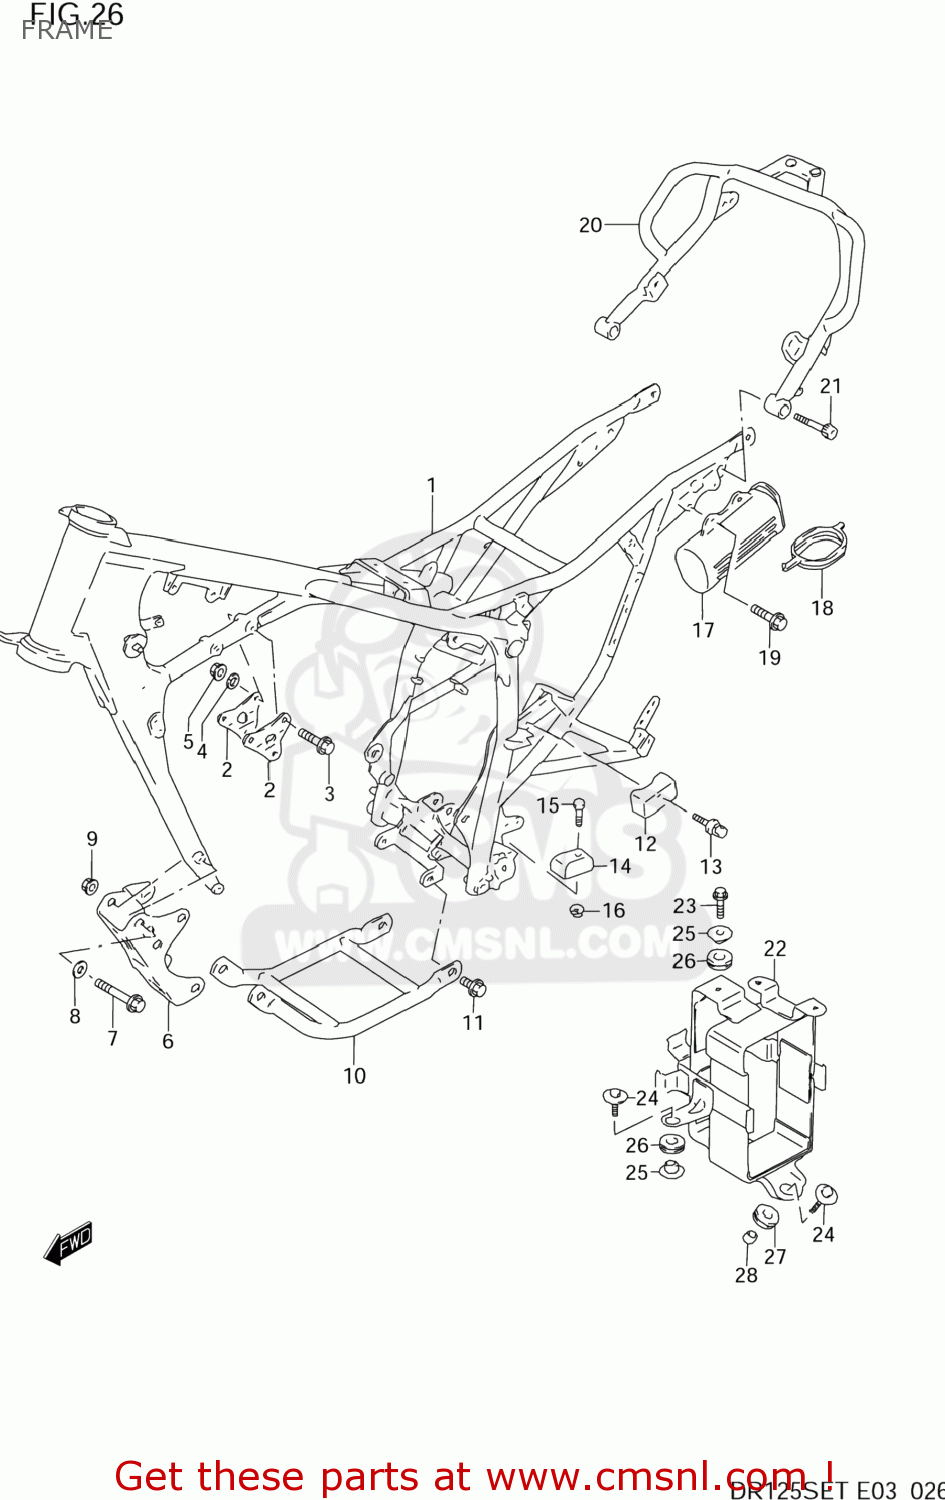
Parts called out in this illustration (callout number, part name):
1	FRAME COMP
2	PLATE,ENGINE MOUNT UPR
3	BOLT M8X52
4	LOCK WASHER
5	NUT
6	PLATE,ENGINE MOUNTING
7	BOLT(8X65)
8	LOCK WASHER
9	NUT
10	PROTECTOR COMP,ENGINE
11	BOLT
12	GUIDE,CH CONTROL UPR
13	BOLT
14	GUIDE,CH LENGTH CONTROL LWR
15	BOLT
16	NUT
17	HOLDER,TOOL
18	CAP,HOLDER
19	BOLT 6X16
20	GRIP,RR
21	BOLT(8X30)
22	HOLDER,BATTERY
23	BOLT
24	BOLT(6X25)
25	SPACER COMP,BATTERY
26	CUSHION
27	CUSHION
28	SPACER (6.8X10X9)
